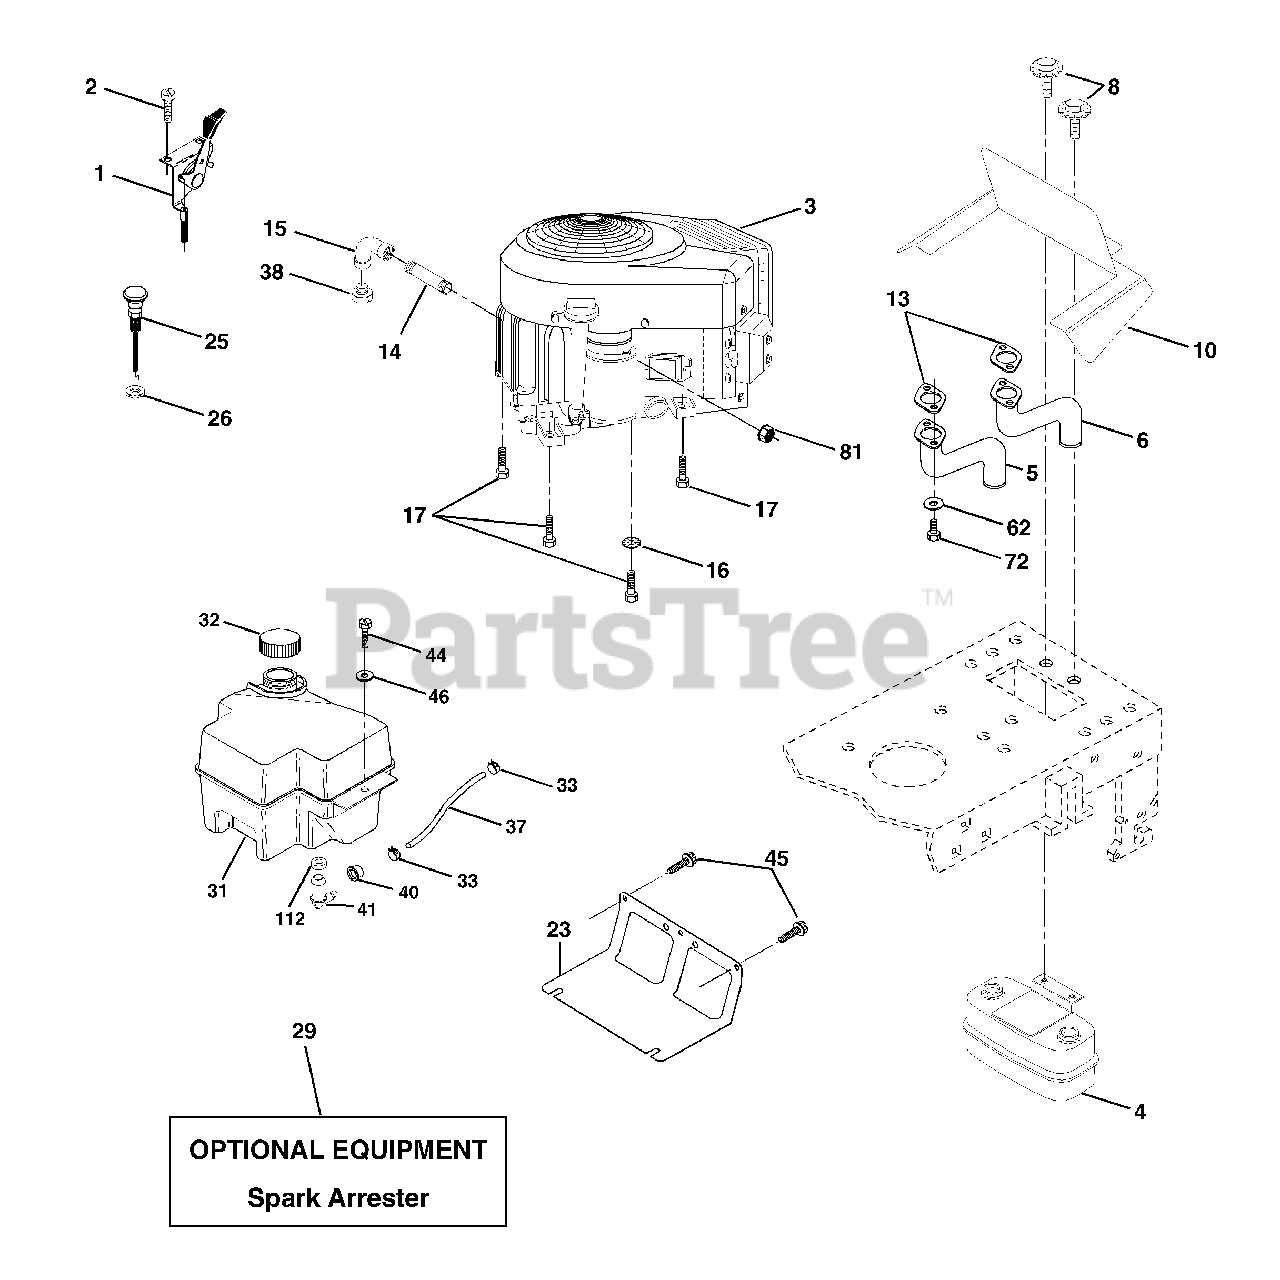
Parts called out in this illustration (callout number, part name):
1	Control, Throttle
2	Screw Hex Thd Cut 1/4-20 x 1/2
4	Muffler, Asm. Twin Lo-Tone
5	Pipe Exhaust Intek 20 RH
6	Pipe Exhaust Intek 20 LH
8	Bolt 5/16-18 UNC x 3/4 w/Sems
10	Shield Browing B&S Intek II
13	Muffler Gasket
14	Nipple Pipe 3/8 NPT x 3"
15	Elbow Std 90 Degree 3/8-18 NPT
16	Washer, Lock Ext tooth 3/8
17	Screw 3/8-16 x 1-1/2
23	Shield, Browning/Debris Guard
25	Control Choke
26	Nut Keps 3/8-24 UNF
29	Arrester, Spark
31	Tank, Fuel
32	Cap Gauge, Fuel
33	Clamp, Hose Blk
37	Line, Fuel 7.5
38	Plug Drain Oil
40	Bushing Snap Nyl Blk Fuel Line
41	Stem Tank Fuel
44	Screw Hex Wsh Thdrol 1/4-20 x 3/4
45	Screw Hex Wsh Thdrol 3/8-16 x 3/4
46	Washer 9/32 x 7/8 x 16 Ga.
62	Washer Lock Hvy Hlcl Spr 5/16
72	Screw Hex Hd Cap 5/16-18 x 3/4
81	Nut Keps Hex 1/4-20 Unc
112	Bushing
